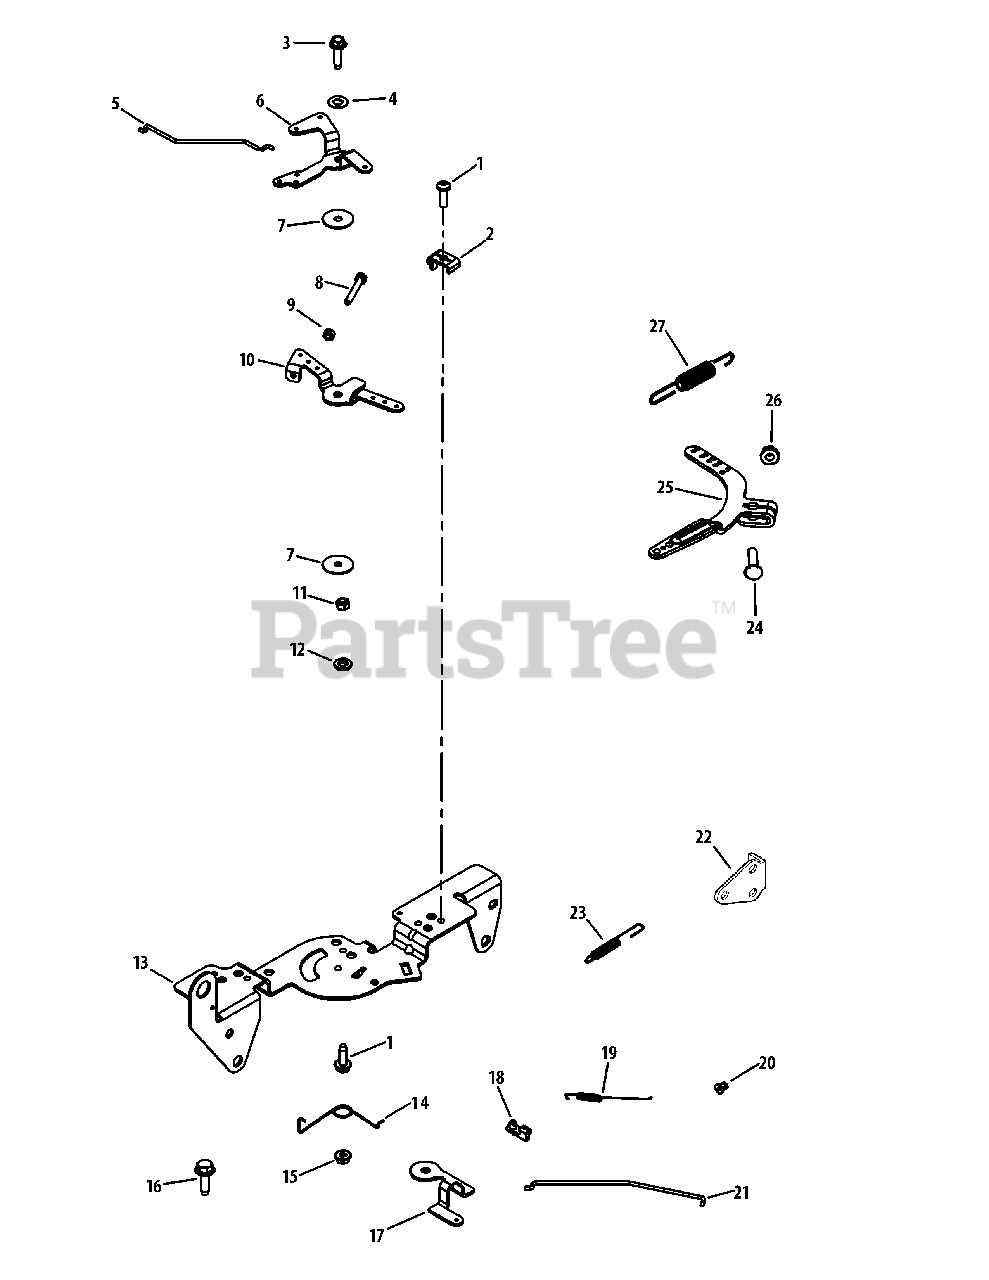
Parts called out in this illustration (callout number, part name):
1	Thread Forming Screw
2	Cable Clamp
3	Thread Forming Screw
4	Spring Washer, 1/4
5	Choke Linkage
7	Flat Washer, 5.5 MM
8	Cap Screw, M4 x .7 x 30
9	Nut, M4 x 0.7
10	Throttle Control Lever
11	Flange Nut, M5 x .8
12	Spring Lock Washer, 1/4
13	Control Bracket
14	Choke Return Spring
15	Lock Nut, M5 x .8
16	Thread Forming Screw
17	Throttle Actuator Lever
18	Throttle Linkage Bushing
19	Linkage Spring
20	Linkage Retaining Bushing
21	Throttle Linkage
23	Throttle Limiter Spring
24	Bolt, M6 x 1.0 x 25
25	Governor Lever
26	Flange Nut, M6 x 1.0
27	Governor Spring (Purple)
